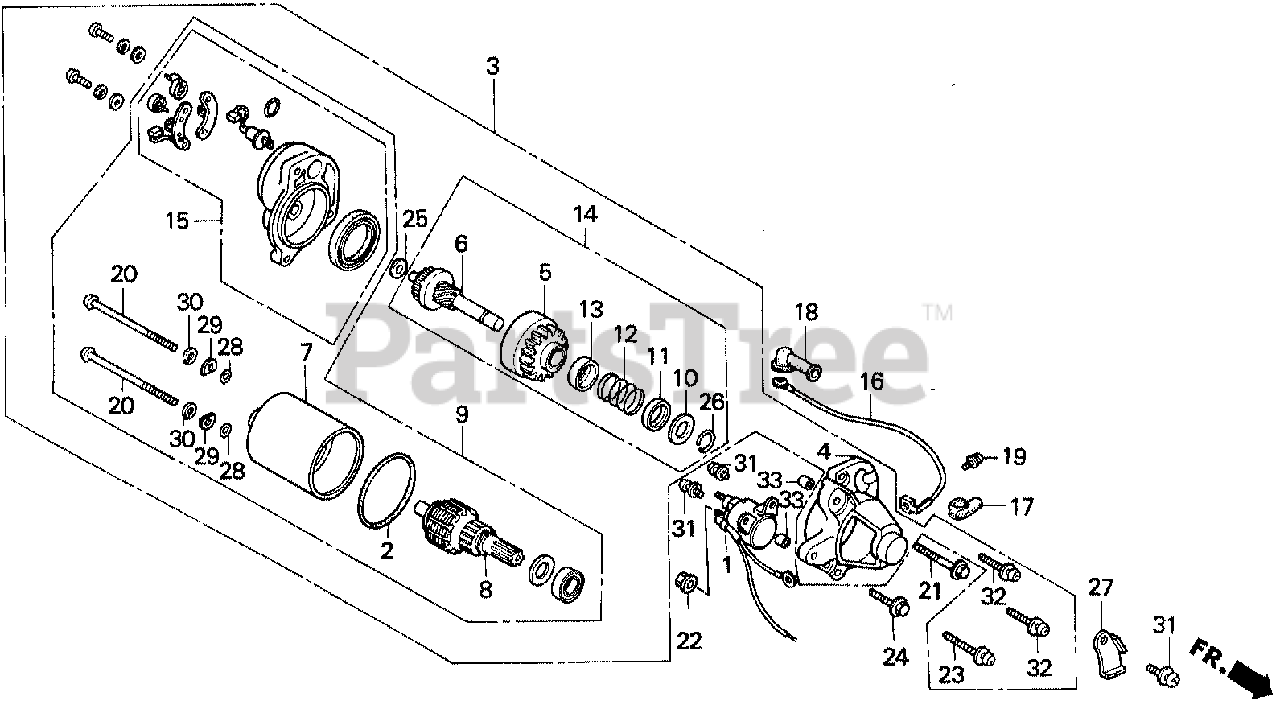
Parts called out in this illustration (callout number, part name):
1	SWITCH, MAGNETIC
2	O-RING
3	MOTOR UNIT, STARTER
4	COVER, GEAR
5	PINION ASSY.
6	SHAFT UNIT, GEAR
7	YOKE ASSY.
8	ROTOR ASSY.
9	MOTOR ONLY
10	PIECE A, STOPPER
11	PIECE B, STOPPER
12	SPRING, RETURN
13	COVER, SPRING
14	GEAR ASSY.
15	BRACKET, FR.
16	WIRE, MAGNET SWITCH
17	COVER, MAGNET SWITCH TERMINAL
18	COVER, STARTER MOTOR TERMINAL
19	SCREW-WASHER (5X8)
20	BOLT, SETTING
21	BOLT, FLANGE (6X32)
22	NUT-WASHER (6MM)
23	SCREW-WASHER (5X30)
24	BOLT, FLANGE (6X25)
25	WASHER, PINION
26	CIRCLIP (10.2MM)
27	HOLDER, HARNESS
28	O-RING
29	WASHER, SPECIAL
30	WASHER, SPRING
31	SCREW-WASHER (5X14)
32	SCREW-WASHER (5X20) (NOT AVAILABLE)
33	PIN A, DOWEL (8X10)
